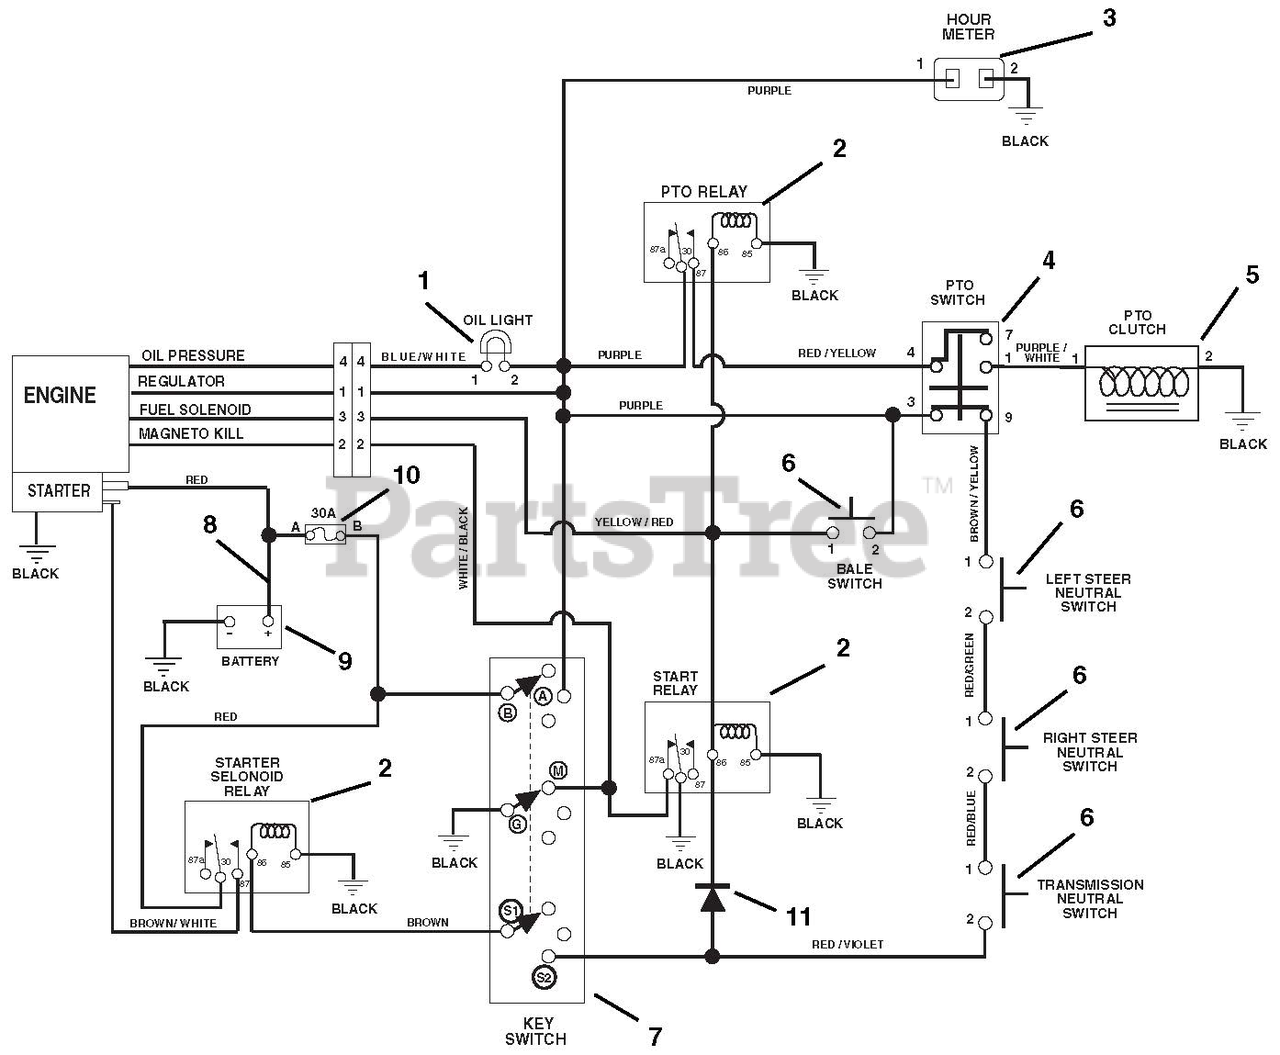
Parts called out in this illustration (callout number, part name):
1	LIGHT, INDICATOR (RED)
2	RELAY
3	METER, HOUR W/MAINTENANCE
4	SWITCH, CLUTCH
5	CLUTCH, ELECTRIC - WARNER
6	SWITCH-SINGLE POLE N.O.W/COVER
7	KEY SWITCH
8	CBL,BATTERY TO SOLENOID
9	CBL,NEGATIVE BATTERY 20.00
10	FUSE, 30 AMP.
11	MOLDED DIODE PLUG 1 AMP
